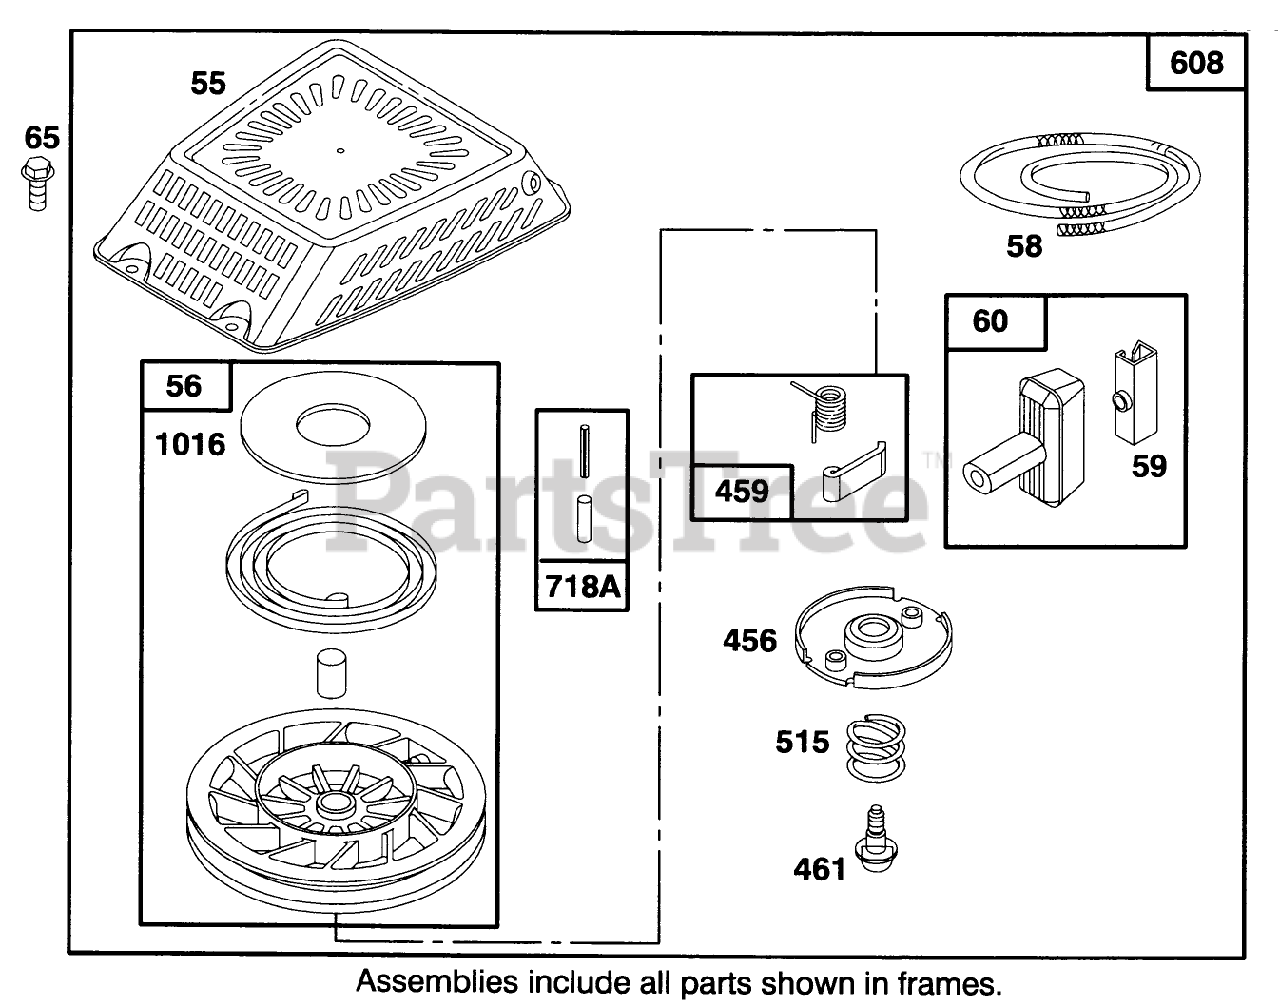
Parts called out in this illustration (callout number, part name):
60	HANDLE-REWIND STARTER
456	RETAINER - SPRING
515	SPRING - RETAINER
